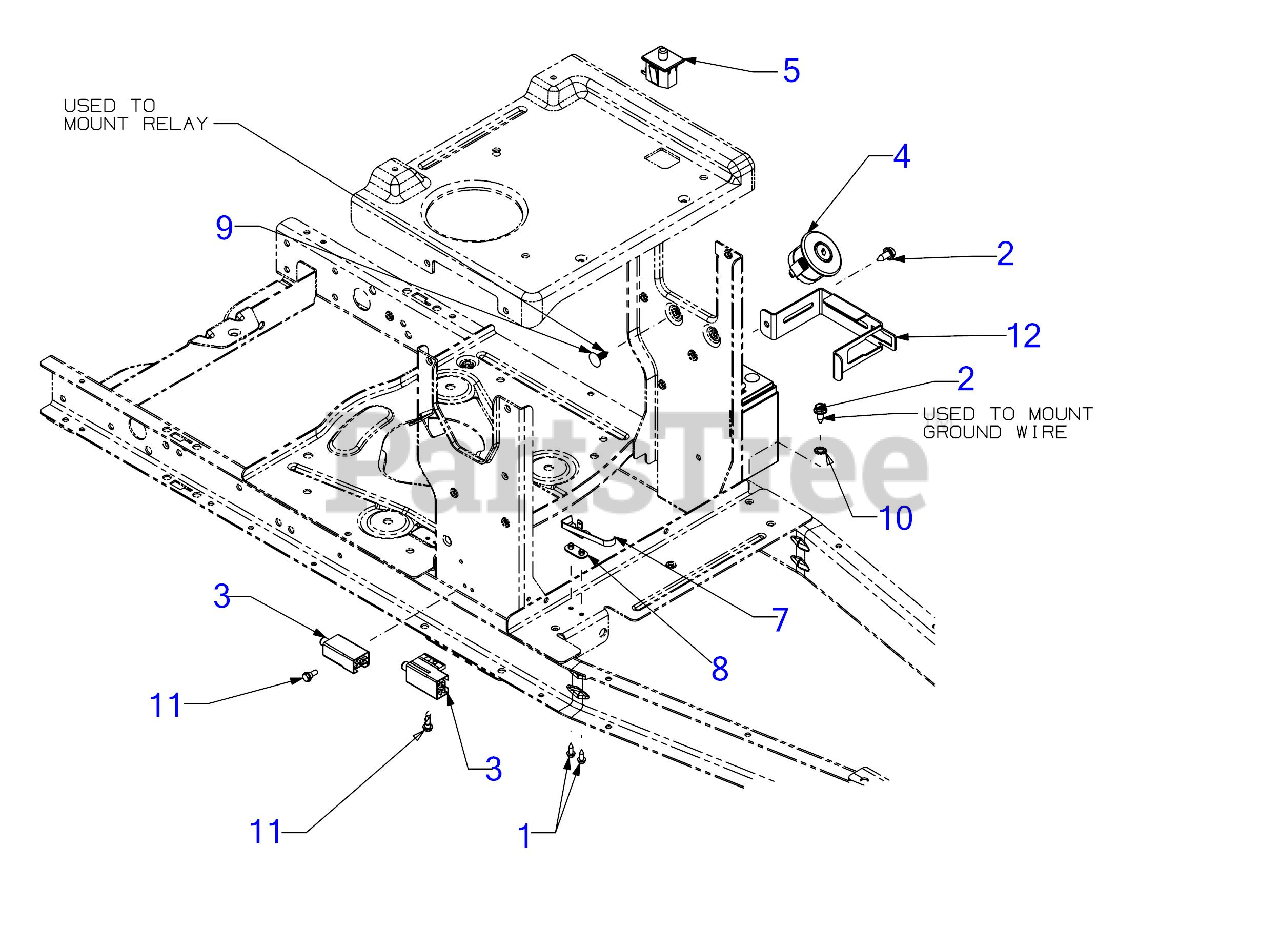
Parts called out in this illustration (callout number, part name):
1	HEX SCREW WASHER HD #8-18 x 0.500
2	SCREW 1/4-20X.625
3	INTERLOCK SWITCH (NO/NC)
4	3 POSITION KEY SWITCH
5	SEAT SWITCH
7	SPRING SWITCH
8	INSULATOR PLATE
9	RATCHET CLIP .250
10	LOCK WASHER 1/4
11	SHOULDER SCREW
12	BATTERY TRAY
